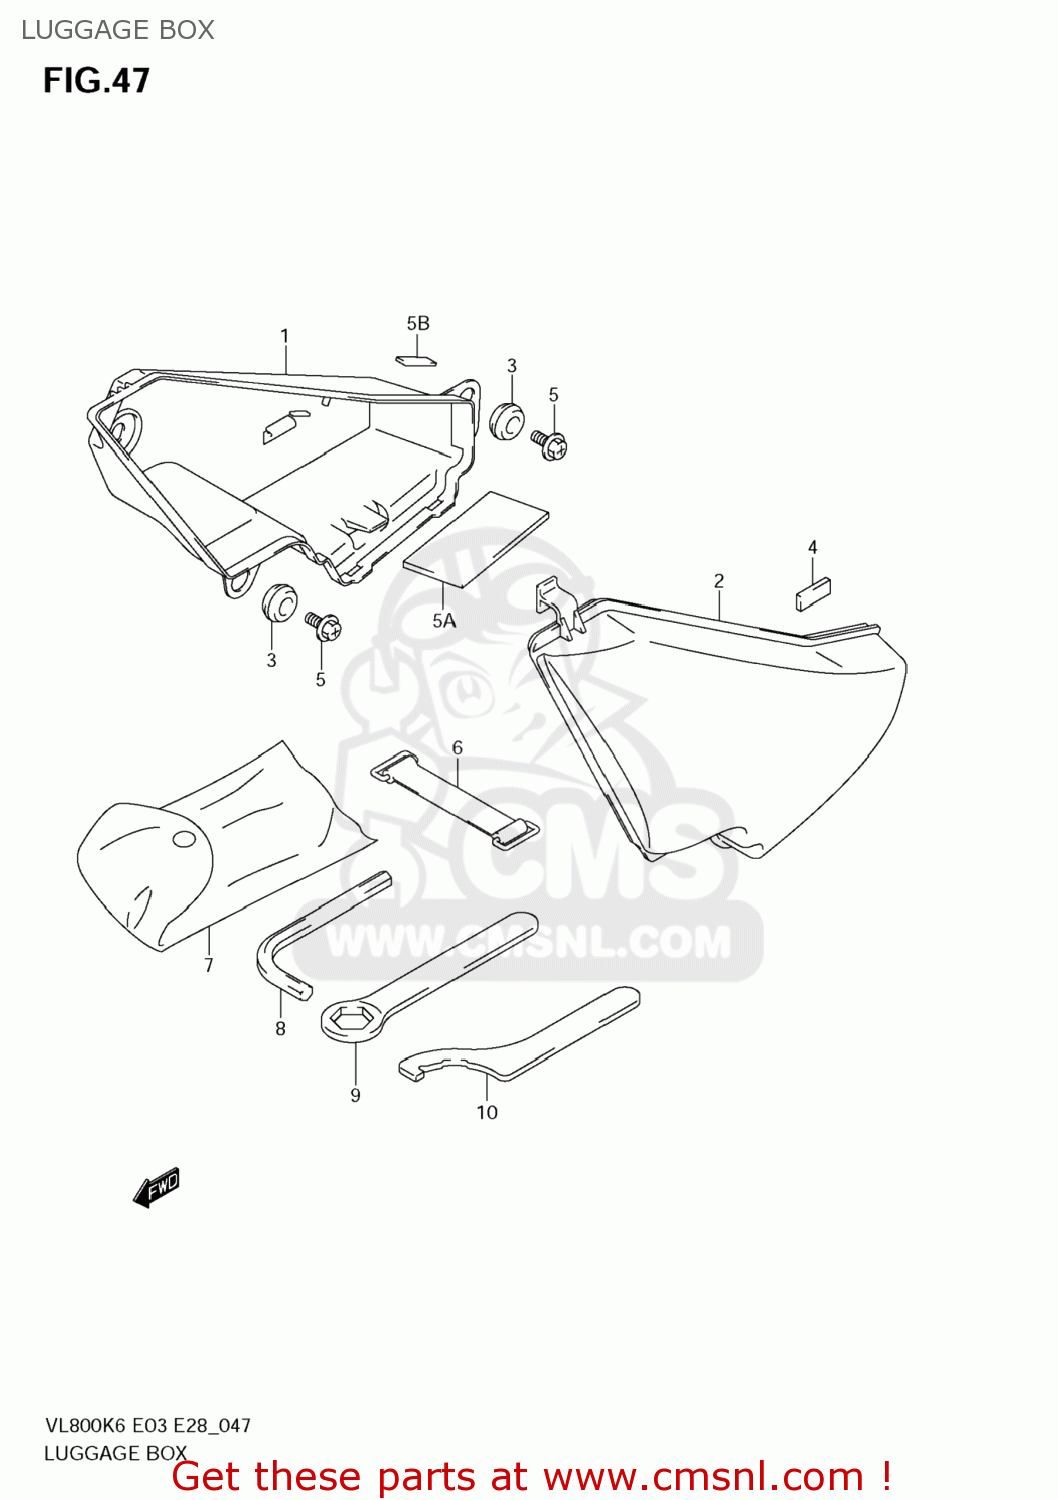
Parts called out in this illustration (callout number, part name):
1	BODY,LUGGAGE BOX
2	LID,LUGGAGE BOX
3	PAD,BALANCER UPPER,R
4	CUSHION,LUGGAGE BOX NO.2
5	BOLT
5A	PROTECTOR,BATTERY
5B	CUSHION
6	O RING(D:3.5,ID:61)
7	TOOL ASSY
8	HEXAGON SPANNER,8
9	RING SPANNER(22)
10	CLAMP
